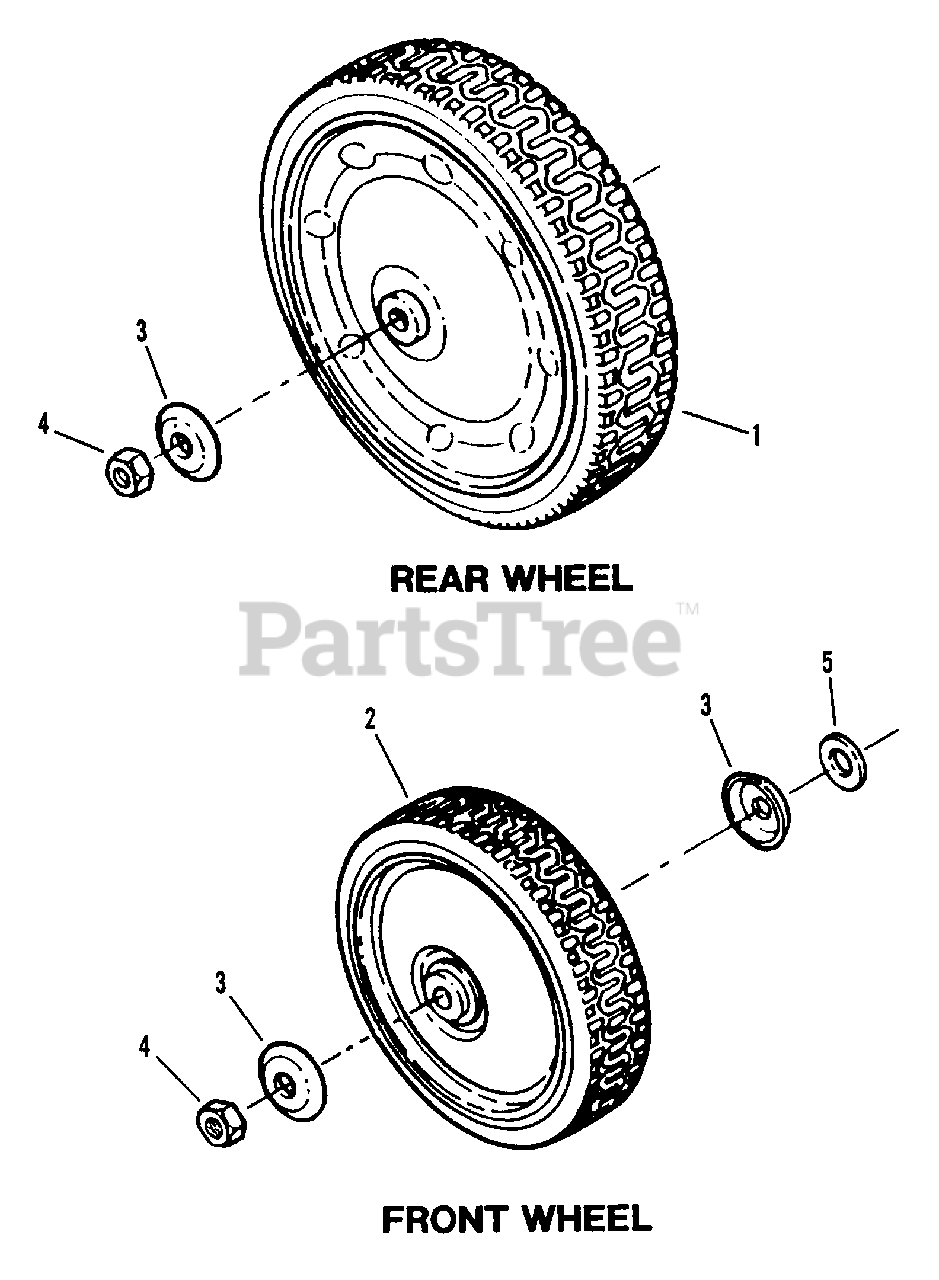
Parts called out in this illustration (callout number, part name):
1	WHEEL, Rear 9.20 x 2.00 Steel Rim
2	WHEEL, Front 8.00 x 2.00 Steel Rim
3	HUB-CAP (Front Wheels)
4	NUT, 7/16-18 Hex Center Lock
5	WASHER, 7/16 Flat
